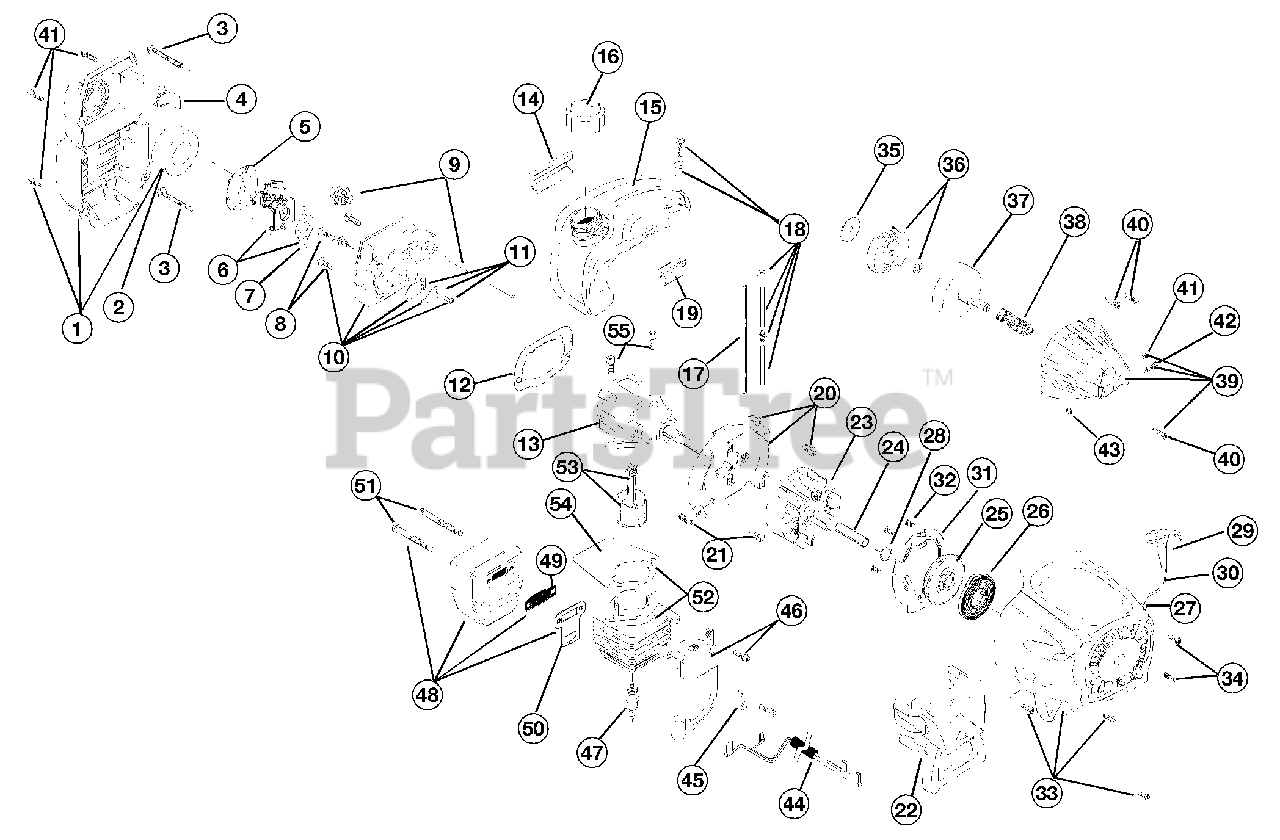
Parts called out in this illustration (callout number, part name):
1	Air Cleaner/Muffler Cover Assembly
2	Air Cleaner Filter
3	Carburetor Mounting Screw Assembly
4	Choke Extension
5	Choke Plate
6	Carburetor Assembly
7	Carburetor Gasket
8	Carb Mount Screw
9	Primer and Hose Assembly
10	Carb Mount Assembly
11	Reed Assembly
12	Carburetor Mount Gasket
13	Crank Case Service Assembly
14	Rear Mounting Pad
15	Fuel Tank Assembly
16	Fuel Cap Assembly
17	Fuel Return Line
18	Fuel Line Assembly
19	Front Mounting Pad
20	Shroud Assembly
21	Shroud Screw
22	Shroud Extension and Stand
23	Flywheel Assembly
25	Recoil Pulley Assembly
26	Recoil Spring
27	Rope Guide
28	Pulley Retainer
29	Pull Handle
31	Pressure Plate Assembly
32	Plate Screw
33	Starter Housing Assembly
34	Housing Screw
35	Clutch Washer
36	Clutch Rotor Assembly
37	Clutch Drum Assembly
39	Clutch Cover Assembly
40	Cover Screw
41	Anti-Rotation Screw
42	Clamping Screw
43	Clamping Nut
44	Wire Leads and Sleeve
45	Ground Tab
46	Module Assembly
48	Muffler Assembly
49	Spark Arrestor Screen
50	Exhaust Gasket
51	Muffler Mounting Bolt Assembly
52	Cylinder Assembly
53	Piston and Rod Assembly
54	Cylinder Gasket
55	Cylinder Bolt
